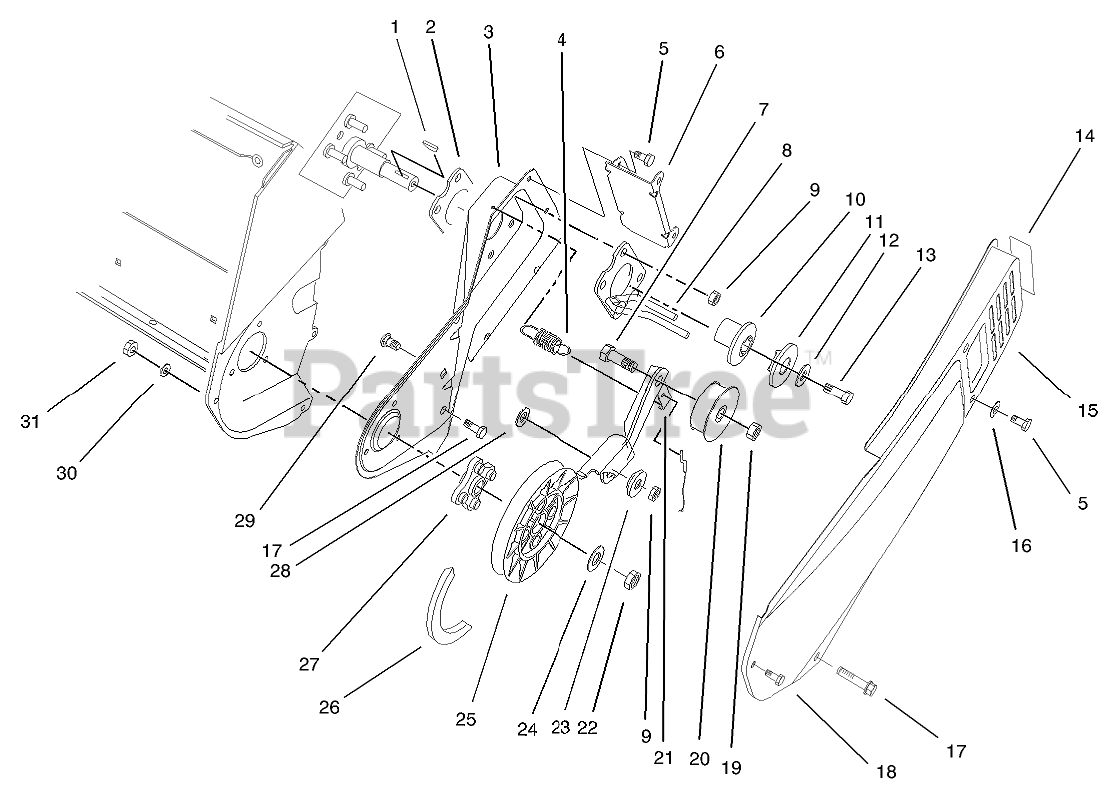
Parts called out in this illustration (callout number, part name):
1	KEY-WOODRUFF
2	PLATE-ENGINE
3	SIDEPLATE-LH
4	SPRING-BRAKE
5	SCREW-HWH
6	BRACKET-COVER, BELT
7	SCREW-HH
8	GUIDE-BELT
9	NUT-LOCK, NI
10	Hub-HALF SHEAVE
11	CAP-HALF SHEAVE
12	WASHER-FLAT
13	SCREW-HH
14	DECAL-HOT
15	COVER-BELT
16	WASHER-FLAT
17	SCREW-PLASTIC
19	NUT-LOCK, NI
20	PULLEY-IDLER
21	ARM-BRAKE
22	NUT-LOCK, NI
23	BUSHING-IDLER
24	WASHER-FLAT
25	PULLEY-DRIVEN
26	V BELT
28	WASHER
29	SCREW-CARR
30	WASHER-FLAT
31	NUT-LOCK, NI
